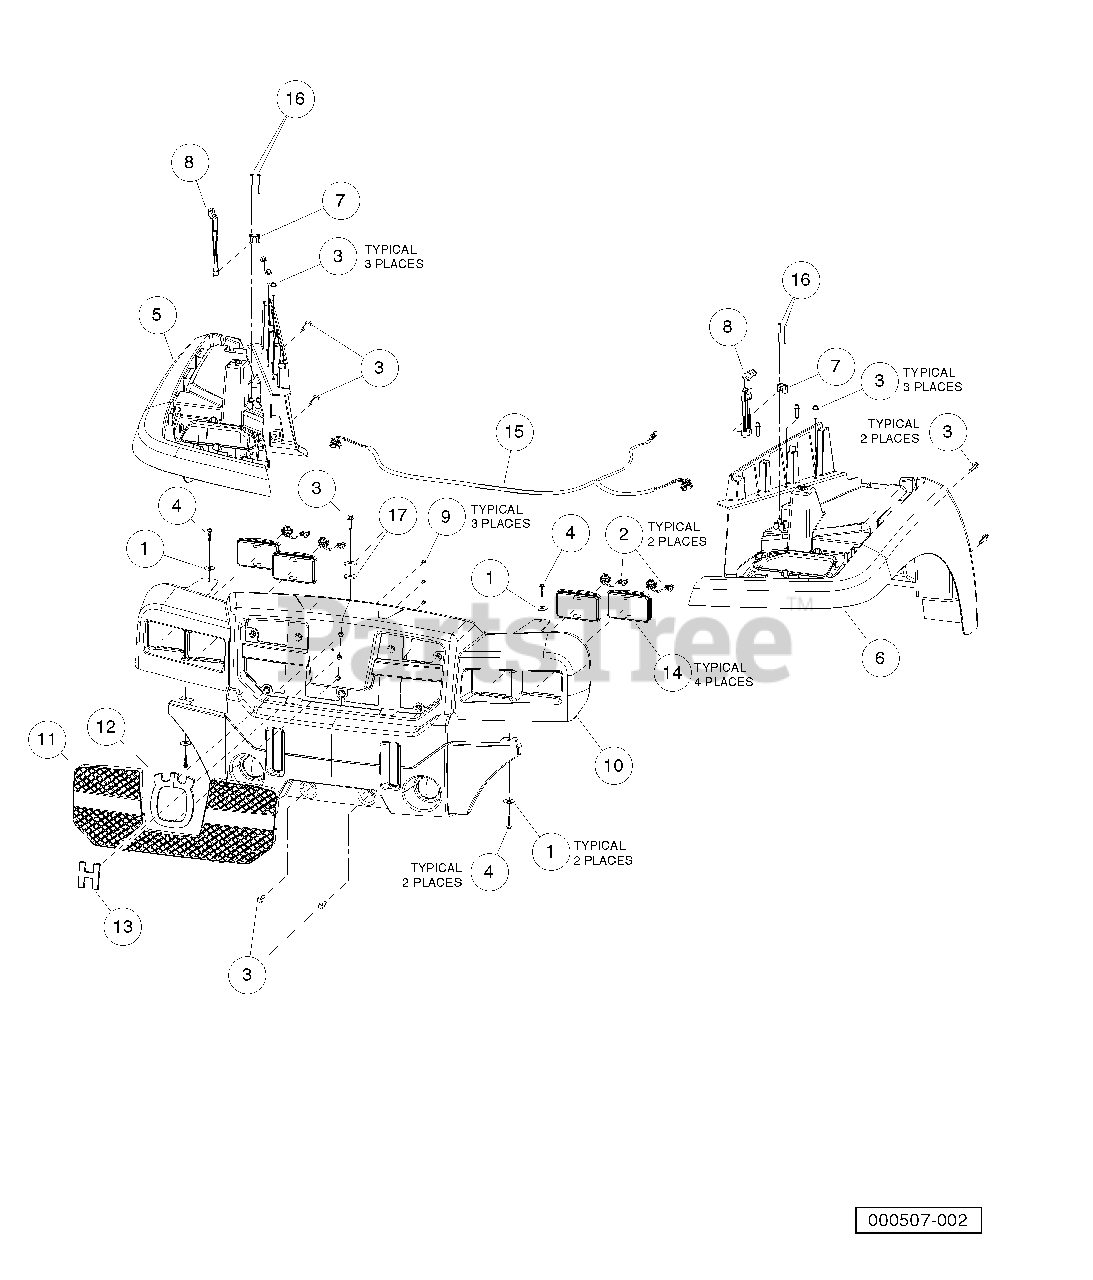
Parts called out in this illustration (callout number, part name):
1	Washer, 5/16 Type B Flat
2	Connector Harness Assembly, Headlight
3	Screw, M8X1.25X30, Hex
4	Screw,m6,torx,interlock,thread
5	Fender, Front, Pass, AWD
6	Fender, Front, Drv, AWD
7	Bracket, Latch, Draw
8	Latch, Draw, Hood
9	Screw, D50x16, Torx PN Hd PT
10	Fascia, Husqvarna
11	Grill, Husqvarna
12	Emblem, Husqvarna, Outer
13	Emblem, Husqvarna, Inner
14	Headlamp, 3x5 Rectangular
15	Harness, Bct/huv Restyle Headlight
16	Screw, #8x2.00 AB Thd, Hex Hd
17	Washer, 3/8 Type B Flat
